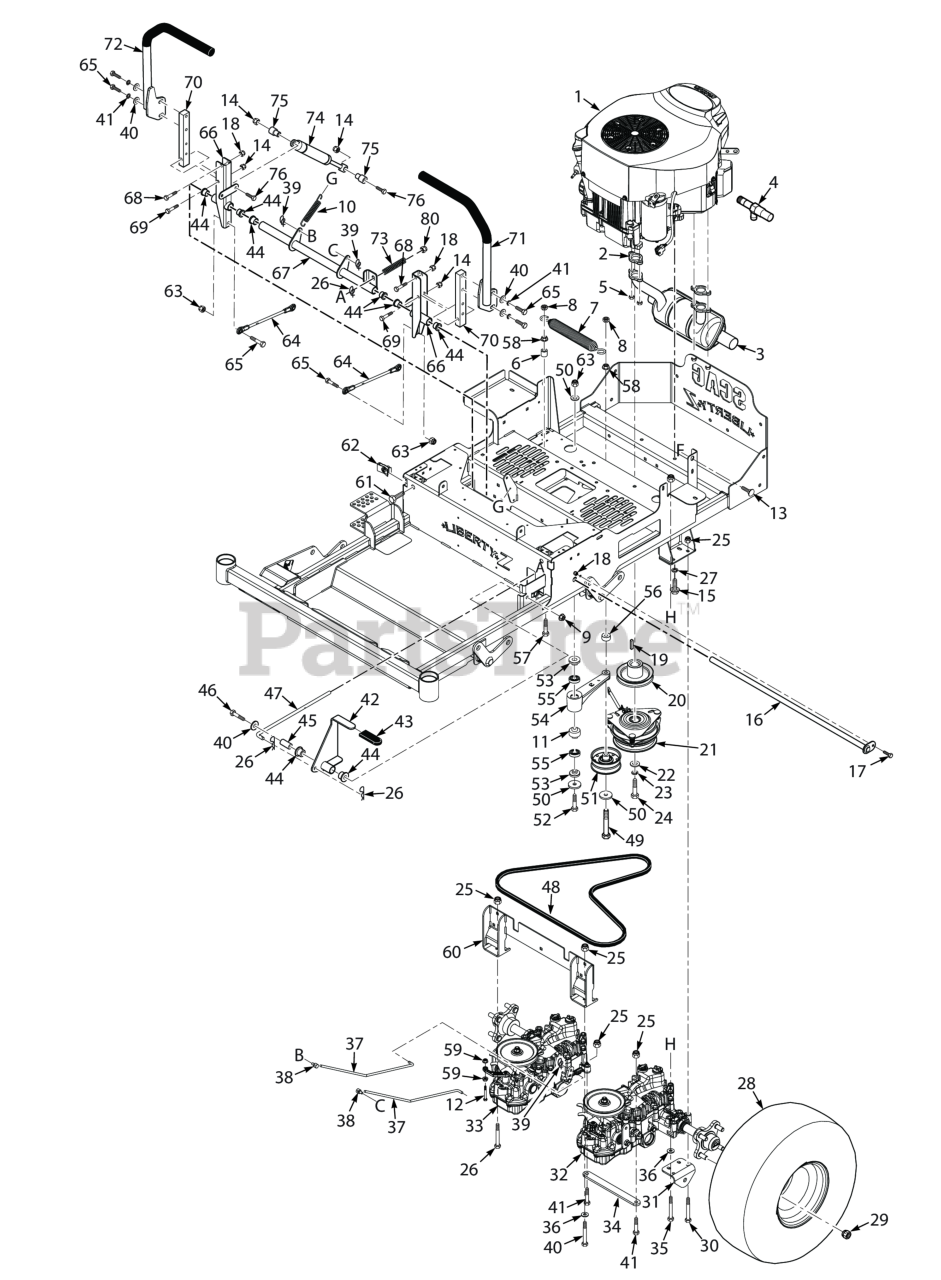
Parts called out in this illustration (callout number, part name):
1	Engine, Kawasaki 21FR
2	Gasket, Exhaust
3	Muffler, Kawasaki FR651V & FR691V
4	Oil Drain, Kawasaki
5	Nut, M8 x 1.25 Hex Special
6	Spacer, Idler Pulley - SFZ52
7	Spring, Transmission Drive
8	Bolt, Hex Head 3/8-16 x 1" Ser. Flg.
9	Nut, Flange Elastic Stop Nut, 3/8-16
10	Spring, Deck Latch
11	Spacer, Bearing
12	Bolt, Hex Head 3/8-16 x 2-1/4" - 61"
13	Serr. Fl. Hex Head CPSCR, 1/4-20 x 3/4"
14	HEX NUT, ELASTIC STOP LOCK, 5/16-18
15	Bolt, Hex Head 3/8-16 x 1-1/4", Kawasaki FX / FT & FT-EFI
16	Shaft Weldment, Control Arm
17	BOLT, HEX HEAD, 1/4-20 X 5/8
18	HEX, NUT, ELASTIC STOP LOCK, 1/4-20
19	Key, 1/4 x 1/4 x 3" (61H)
20	Pulley, 4-1/2" - 1" Bore
21	Clutch
22	Lockwasher, 7/16� Spring
23	Bolt, Hex Head 7/16-20 x 3¼" w/Patch
24	Bolt, Hex Head 7/16-20 x 3¼" w/Patch
25	Nut, Flange Head Elastic Stop 5/16-18
26	BOLT, HEX HEAD, 5/16-18 X 2-1/4
27	Lockwasher, 3/8" Spring, Kawasaki FX / FT & FT-EFI / B&S 32BV
28	Wheel Assembly (48, 52)
29	Wheel Nut, 1/2-20 x 13/16
30	Bolt, Hex Head 5/16-18 x 3.00"
31	Bracket, Pusharm
32	Transaxle - Tuff Torq, LH - SZL
33	Transaxle - Tuff Torq, RH - SZL
34	Stiffener, Axle
35	BOLT, HEX HEAD, 5/16-18 X 2-1/4
36	Flatwasher, 5/16-.375 x .875 x .083 (35BV & 37BV-EFI)
37	Rod, Brake - LH
38	Joint, Swivel
39	Pin, Rue Cotter 3/8" Diameter
40	BOLT, HEX HEAD, 5/16-18 X 2-1/4
41	Bolt, Hex Head 3/8-16 x 1-3/4" (Kohler EFI)
42	Brake Lever Assembly
43	Grip, Brake Handle
44	Bearing
45	Pivot, Brake Lever
46	Capscrew, Hex Head 3/8-16 x 2-1/2"
47	Rod, Upper Brake Linkage
48	Belt, Tuff Torq Transmission-SZL
49	Capscrew, Hex Head 3/8-16 x 3-3/4"
50	Flatwasher, 3/8 (.391 x .938 x .105 HD) Grade 8
51	Pulley, 3-1/2" Dia.
52	Bolt, Hex Head 3/8-16 x 3" - 52"
53	Spacer, Controls
54	Trans. Idler Arm Assy. (Includes 24, 79)
55	BEARINGS, BALL, NEUTRAL RETURN
56	Spacer, Idler Pulley - SFZ61
57	Capscrew, Hex Head 3/8-16 x 2.0"
58	NUT, 3/8-16 SERRATED FLANGE HEX HEAD
59	NUT, 1/4-20 SERRATED FLANGE HEX HEAD
60	Mounting Weldment, Axle - Tuff Torq
61	Bolt, Hex Head 3/8-16 x 2-1/2" Soecial Lock
62	U-Nut, 3/8-16
63	HEX NUT, ELASTIC STOP LOCK, 3/8-16
64	Linkage, Pump
65	Bolt, Hex Head 3/8-16 x 1-1/4", Kawasaki FX / FT & FT-EFI
66	Control Arm Assembly
67	Bellcrank Assembly (incl. 44)
68	Bolt, Hex Head, 1/4-20 x 1-1/4"
69	Bolt, Hex Head 5/16-18 x 1-1/2" - Front
70	Bar, Control Lever
71	Handlebar w/Grip
72	Handlebar w/Grip
73	Spring, Brake
74	Damper, Steering
75	Spacer, Pump Dampener
76	Bolt, Hex Head 5/16-18 x 1-1/2" (Right Front Engine Mounting, Briggs and Kohler Only)
